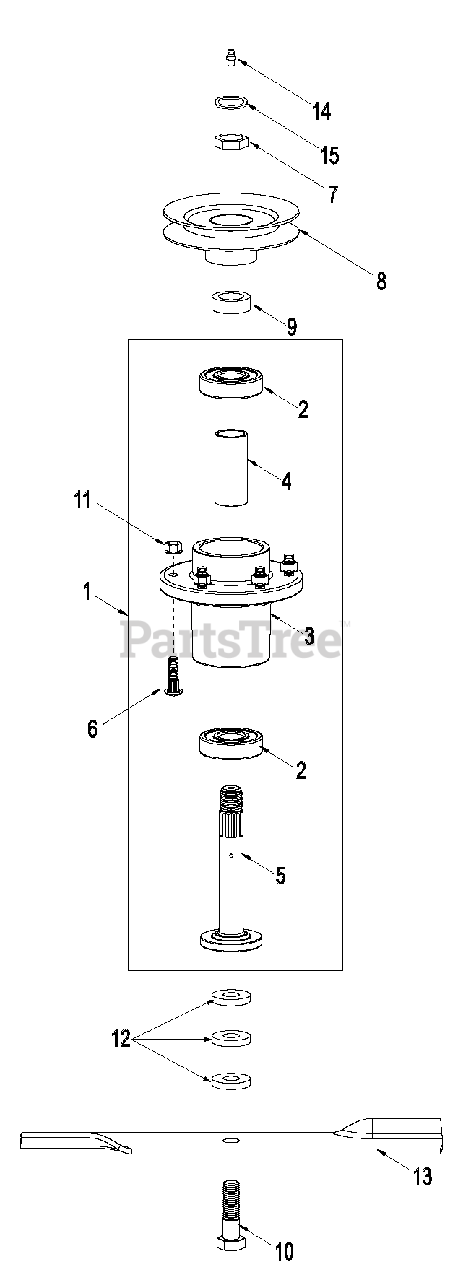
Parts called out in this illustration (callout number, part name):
1	Spindle Assembly - Includes items 2, 3, 4, 5, 6, 14
2	Ball Bearing
3	Housing
4	Spacer - 1.000 x 1.250 x 2.772
5	Shaft, Spindle
6	Bolt, 3/8-16 x 1.25 Rib
7	Nut, Pulley (Special)
8	Pulley, Cutter Housing - See Mower Assembly Pages
9	Spacer, Pulley
10	Bolt, Blade - 5/8-11 x 2.00 Grade 8
11	Nut, 3/8-16 Std Hex Gr5
12	Spacer, Blade Bolt
13	18.0" Blade, LH Deck
14	Zerk, Grease S/O
15	Retainer Nut
